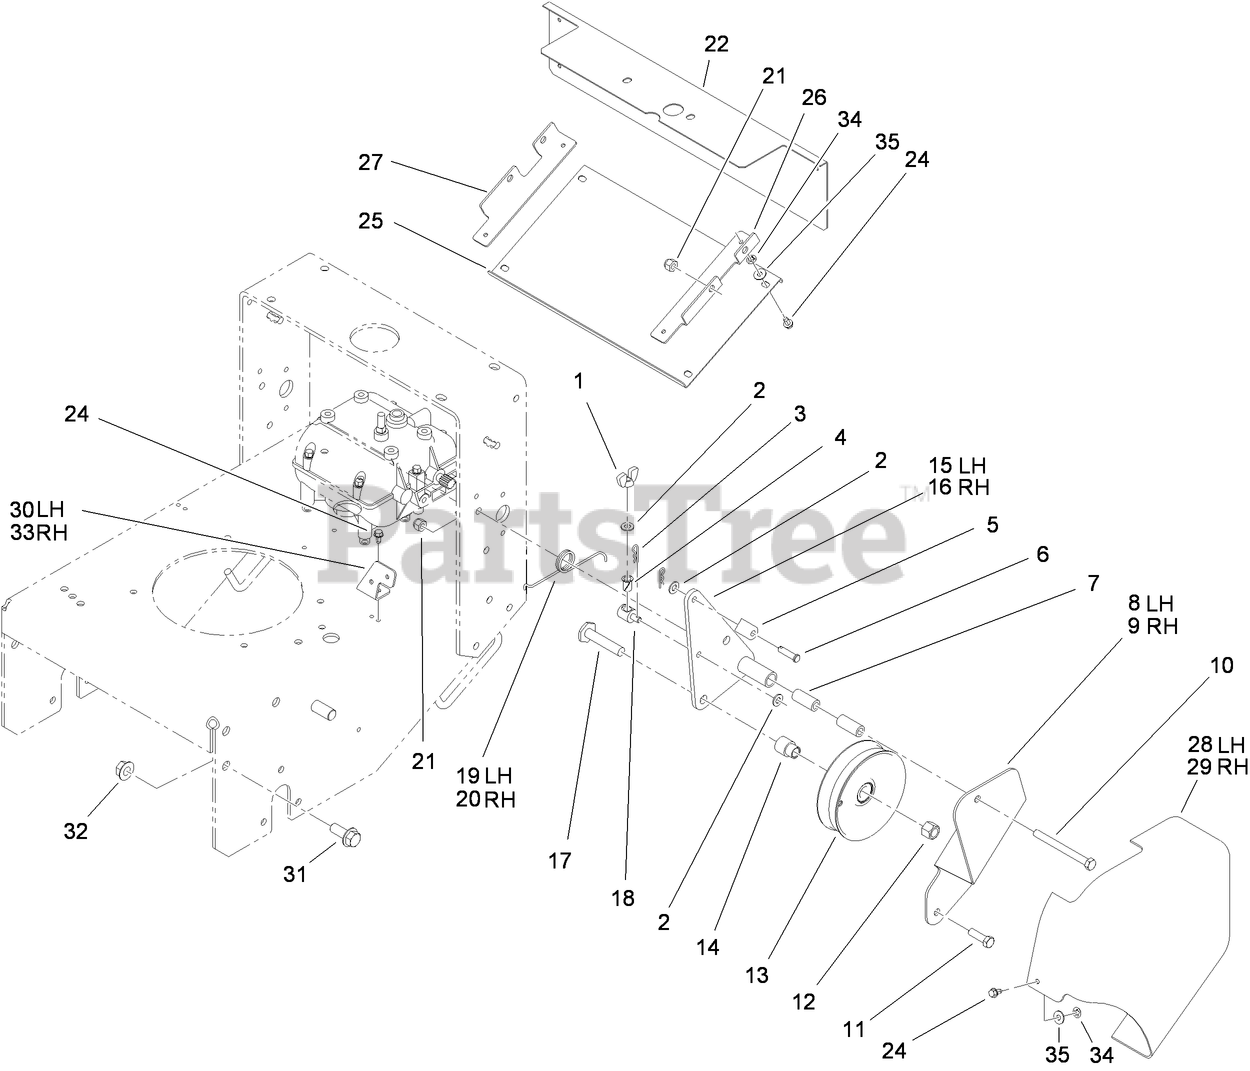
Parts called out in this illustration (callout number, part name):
1	NUT-WING
2	WASHER-PLAIN
3	PIN-COTTER
4	BUSHING-NYLON
5	FITTING-ROD
6	PIN-CLEVIS
7	SPACER-PIVOT, IDLER
8	SUPPORT-IDLER, LH
9	SUPPORT-IDLER, RH
10	SCREW-HH
11	SCREW-HH
12	NUT-LOCK, NI
13	PULLEY-IDLER
14	SPACER-PULLEY
15	ARM-IDLER, LH
16	ARM-IDLER, RH
17	SCREW-LEVELER
18	FITTING-ROD
19	SPRING-TORSION, LH
20	SPRING-TORSION, RH
21	NUT-LOCK, NI
22	GUARD-SHAFT, TRANSMISSION
24	SCREW
25	PANEL-BOTTOM
26	ANGLE-MOUNTING, LEFT
27	ANGLE-MOUNTING, RIGHT
28	GUARD-BELT, LH
29	GUARD-BELT, RH
30	BRACKET-MOUNTING, LH
31	SCREW-HHF
32	NUT-HF
33	BRACKET-MOUNTING, RH
34	NUT-RETAINER
35	WASHER-FLAT
